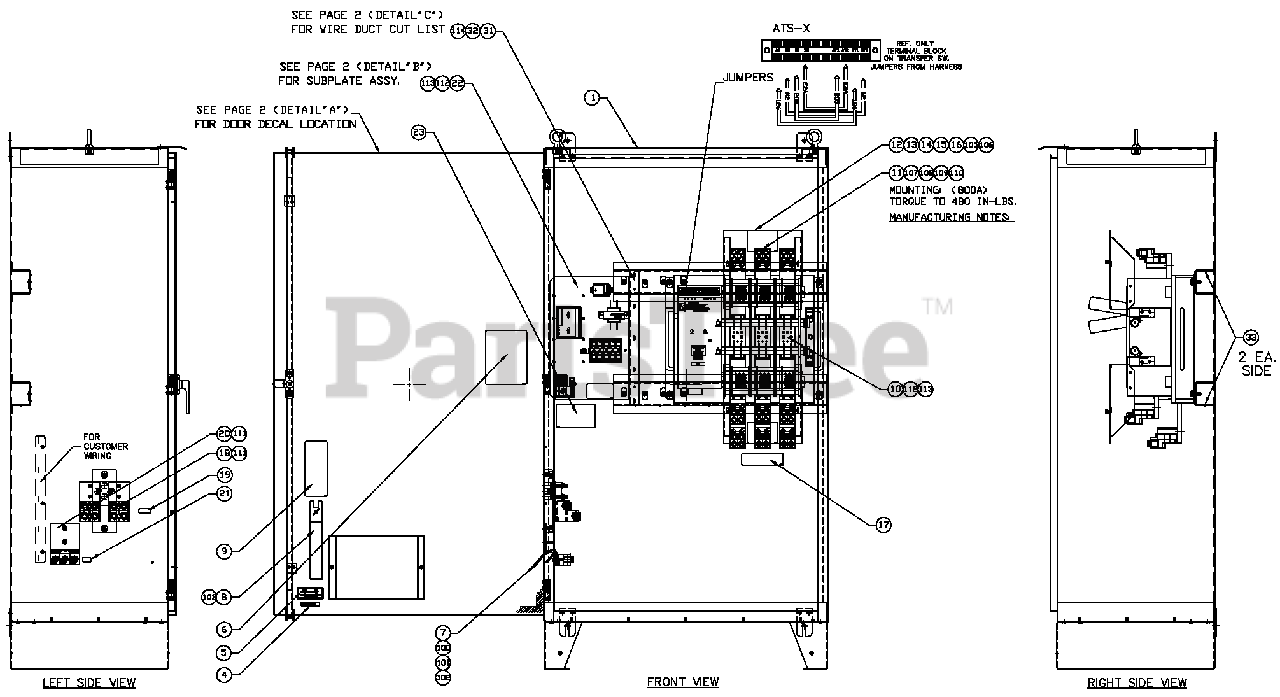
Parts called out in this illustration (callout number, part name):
1	ENCL NEMA 3R 36 X 60 X 20 RTS
4	DECAL ENCLOSURE NOTE NEMA 3R
5	DECAL UL CONTROL PANEL ENCL.
6	DECAL RTS TEST SEQUENCE 800A
7	ASSY WIRE #0 12.00" (GROUND WIRE)
8	MNL HNDL 6-1600A WN (SUPPLIED W/ SWITCH)
9	DECAL MANUAL OPERATION
10	XFRSW 800A 3P WN600V
11	LUG SLDLSS 500- 4/0X17/32 AL/CU
12	SW CVR WN 800/1000A 3P
13	CVR BKRT 600-1600A RH
14	CVR BKRT 600-1600A LH
15	KNOB, COVER HOLD-DOWN
16	DECAL TERMINAL SHOCK HAZARD
17	DECAL TERMINAL NOTE
18	ASSY NEUTRAL BLK 600-1000A ATS
19	DECAL NEUTRAL
20	ASSY GRD. TERM. 600-2600A
21	DECAL GROUND LUG
22	SUB-PLATE RTS 600-800A
23	PLATE DATA - RTS
31	DUCT WIRING 1 X 1.5 (17"LG)
32	COVER WIRE DUCT 1 IN (17"LG)
33	TIE-WRAP MOUNT(FIR TREE SYTLE)
100	WASHER FLAT #8 ZINC
101	WASHER LOCK #8-M4
102	NUT HEX M4-0.7 G8 YEL CHR
103	NUT WING M6-1.0
105	WASHER LOCK #10
106	WASHER SHAKEPROOF EXT 5/16 STL
107	WASHER LOCK 7/16
108	SCREW HHC 7/16-14 X 1-3/4 G5
109	NUT HEX 7/16-14 STEEL
110	SCREW HHTT #8-32 X 1/4 CZ
111	NUT HEX FL WHIZ M8-1.25
112	SCREW HHC M10-1.5 X 30 G8.8
113	WASHER LOCK M10
114	RIVET WIRE DUCT MNT
